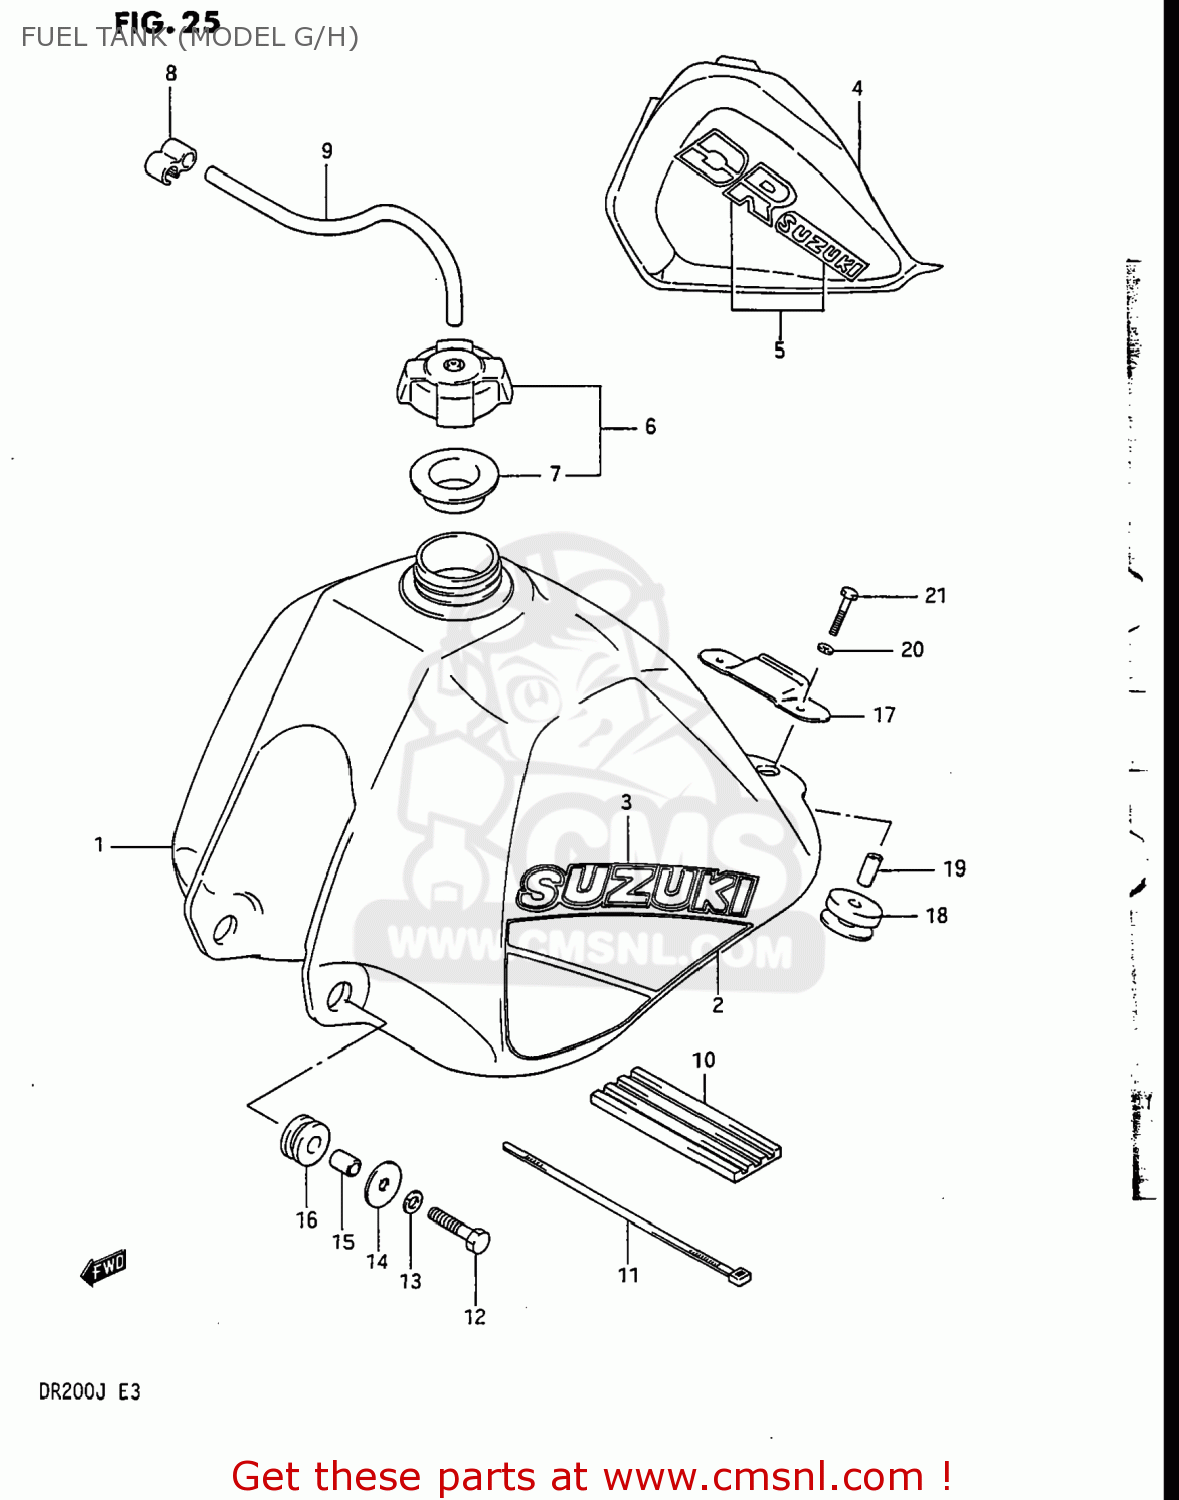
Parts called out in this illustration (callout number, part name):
1	TANK ASSEMBLY,FUEL
2	TAPE SET,FUEL TANK
3	EMBLEM
4	TANK ASSEMBLY,FUEL
5	TAPE SET,FUEL TANK
6	CAP SET,FUEL TANK
7	GASKET,FUEL TANK CAP (NAS)
8	CLAMP,FUEL TANK BREATHER HOSE
9	HOSE
10	CUSHION,FUEL TANK UPR FR
11	CLAMP
12	BOLT
13	LOCK WASHER
14	WASHER (8.5X29X1.6)
15	SPACER (8.8X12X13.5)
16	CUSHION
17	PLATE,SEAT FR HOOK
18	CUSHION
19	SPACER
20	WASHER,LOCK
21	BOLT
